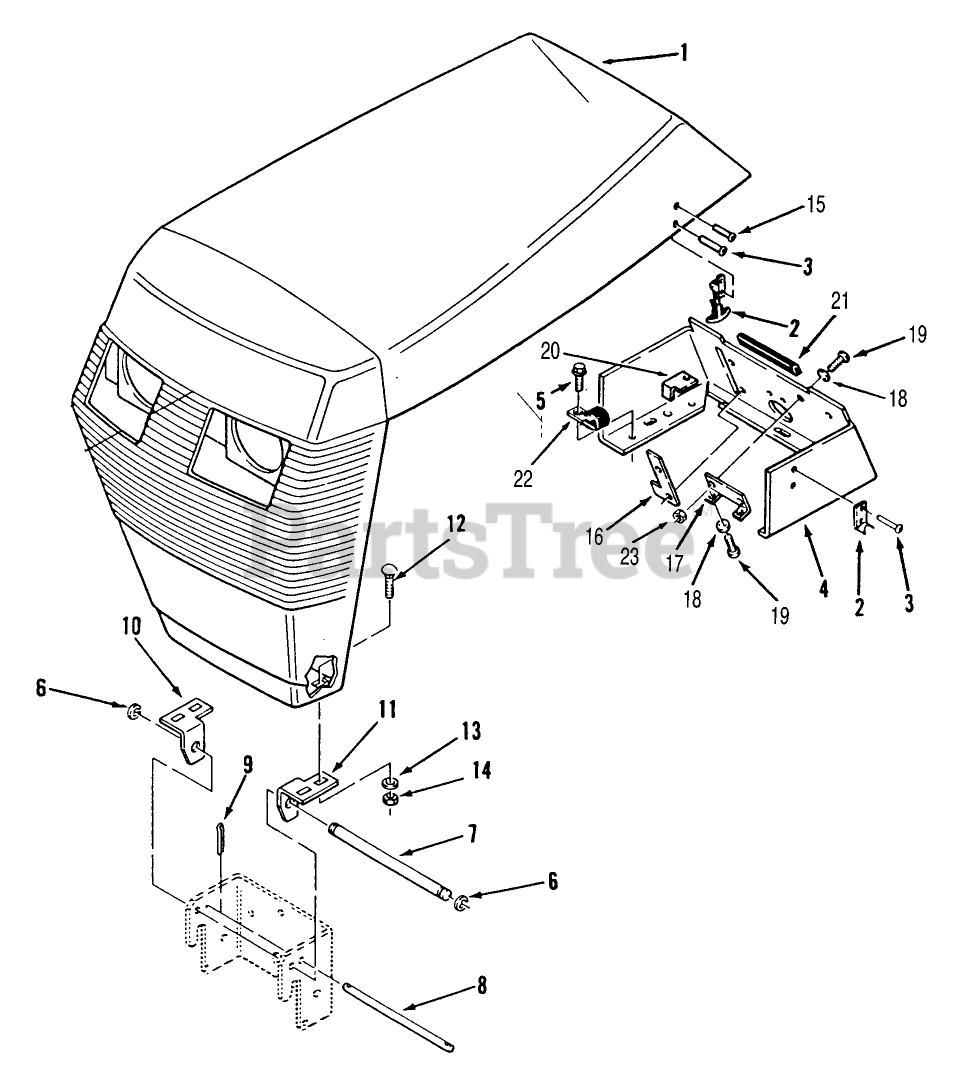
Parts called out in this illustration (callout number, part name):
2	ASSY-FLEX DRAW LATCH
3	RIVET-POP
5	SCREW
6	RING-RETAINING
7	ROD-GRILL PIVOT
8	ROD-HOOD STOP
10	BRACKET-GRILL, R H
11	BRACKET-GRILL, LH
16	STOP THROTTLE
17	BRACKET
19	SCREW-PAN
20	STOP-PTO
21	EDGING-CONSOLE
22	J-CLIP
